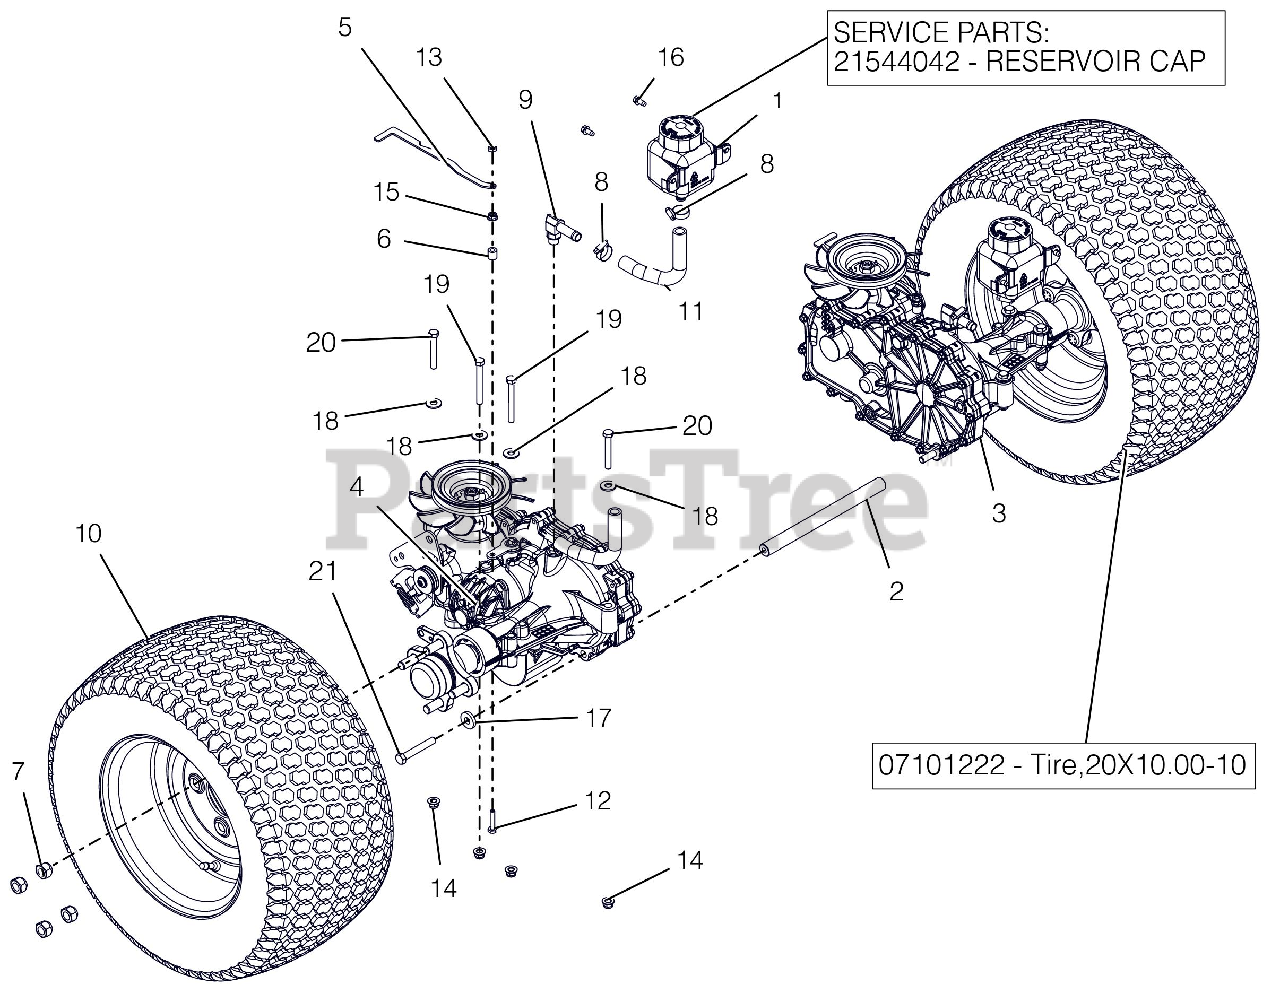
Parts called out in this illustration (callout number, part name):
1	TANK, EXPANSION
1	CAP, HYDRO RESERVOIR REPLAC.
2	ROD, TRANSAXLE BRACE (LONG)
3	TRANSAXLE,ZT2800 LH
4	TRANSAXLE,ZT2800 RH
5	BRKT, DUMP VALVE
6	BSHG-SLV .265X.500X.500
7	WHEEL NUT .500-20 YZ
8	CLAMP,.88 DIA. HOSE
9	FITTING, HYD (90 DEG)
10	ASM, WHL/TIRE 20X10.00-10
10	TIRE, 20X10.00-10 (OTR)
11	HOSE, FORMED LH XL
12	@BLT-HEX .25-20X1.25 GR5 YWZC
13	NUT-LK-CTR JAM .25-20 YWZC
14	@NUT-LK-NYL-FLG .31-18 YWZC
15	@NUT-SPNLK-FLG .25-20 YWZC
16	SCR-TAP .25-20X.50 HWH TR YWZ
17	WSHR-FL-STL .406X1.00X.188 YWZ
18	@WSHR-FL-STL.38X.875X.083 YWZC
19	@BLT-HEX .31-18X2.75 GR5 YWZC
20	@BLT-HEX .31-18X2.25 GR5 YWZC
21	@BLT-HEX .38-16X2.50 GR5 YWZC
